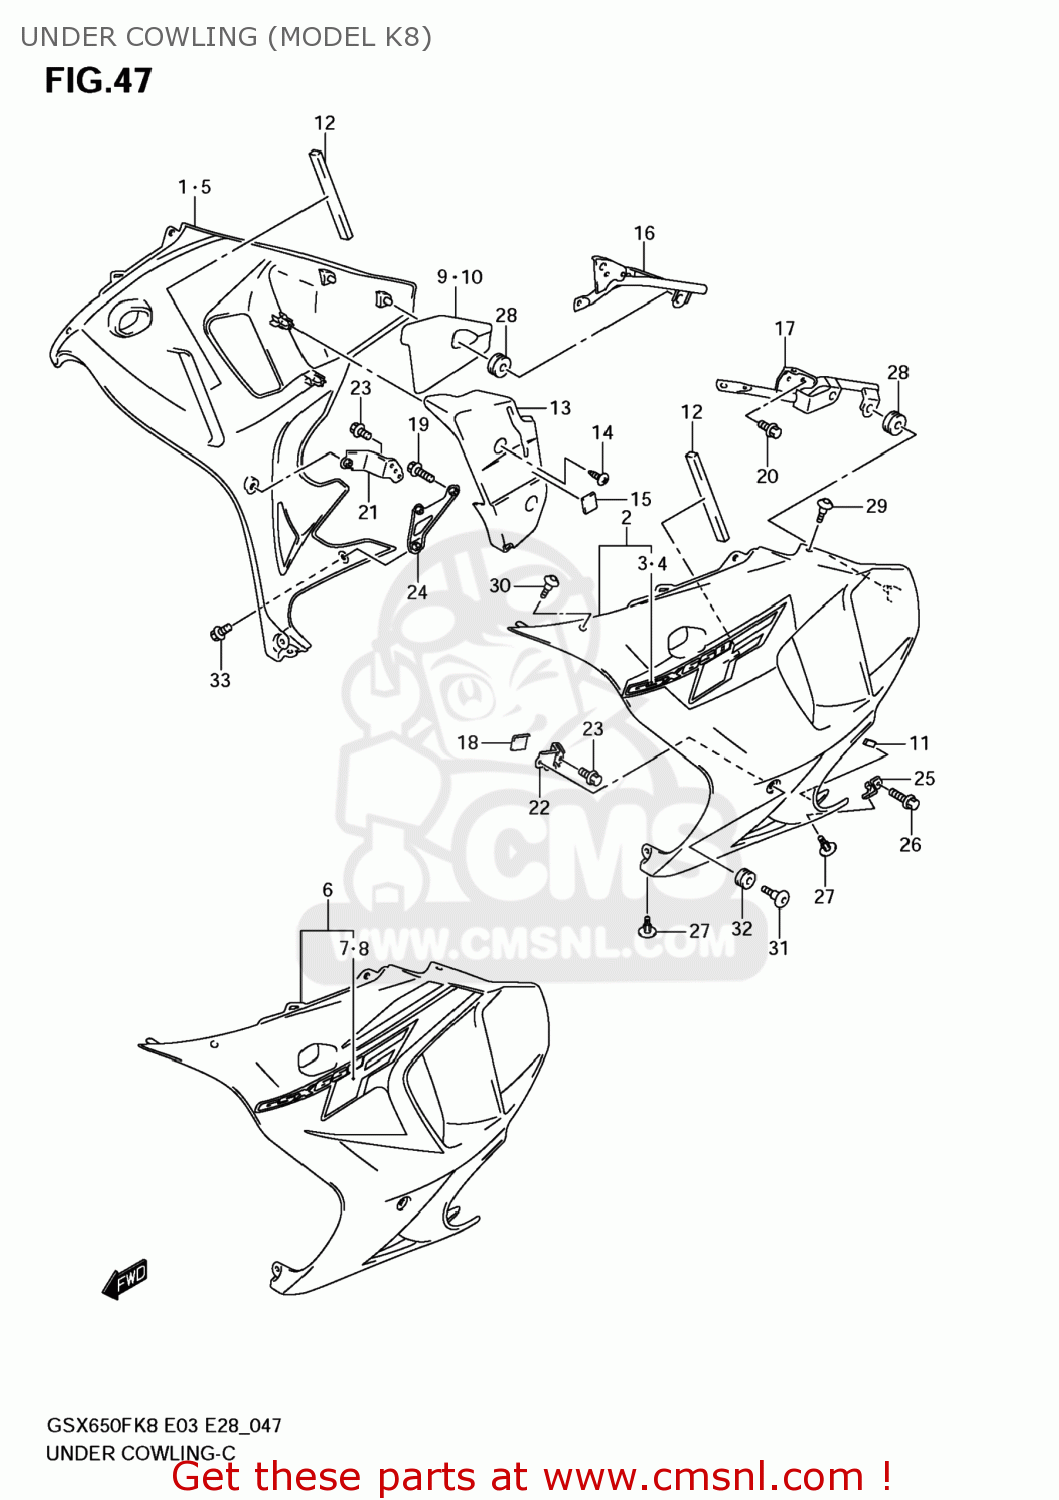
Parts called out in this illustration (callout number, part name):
1	COWLING,UNDER,R(BLACK)
2	COWLING,UNDER,L(BLACK)
3	EMBLEM,UNDER COWLING,R
4	EMBLEM,UNDER COWLING,L
5	COWLING,UNDER,R
6	COWLING,UNDER,L
7	TAPE,UNDER COWL,R
8	TAPE,UNDER COWL,L
9	SHIELD,UNDER COWL HEAT,R
10	SHIELD,UNDER COWL HEAT,L
11	CUSHION,LICENSE PLATE
12	CUSHION,UNDER COWLING
13	PROTECTOR,COWLING UNDER,R
14	SCREW
15	CUSHION,UNDER COWL ENG,R NO.1
16	BRACKET,COWLING FITTING,R
17	BRACKET,COWLING FITTING,L
18	PROTECTOR,COWLING UNDER
19	BOLT
20	BOLT
21	BRACKET,UNDER COWLING FR,R
22	BRACKET,UNDER COWLING FR,L
23	BOLT
24	BRACKET,UNDER COWLING LWR,R
25	BRACKET,UNDER COWLING LWR,L
26	BOLT
27	CLIP
28	CUSHION
29	SCREW(5X16)
30	SCREW(5X13)
31	SCREW(6X20)
32	CUSHION
33	SCREW(6X12)
